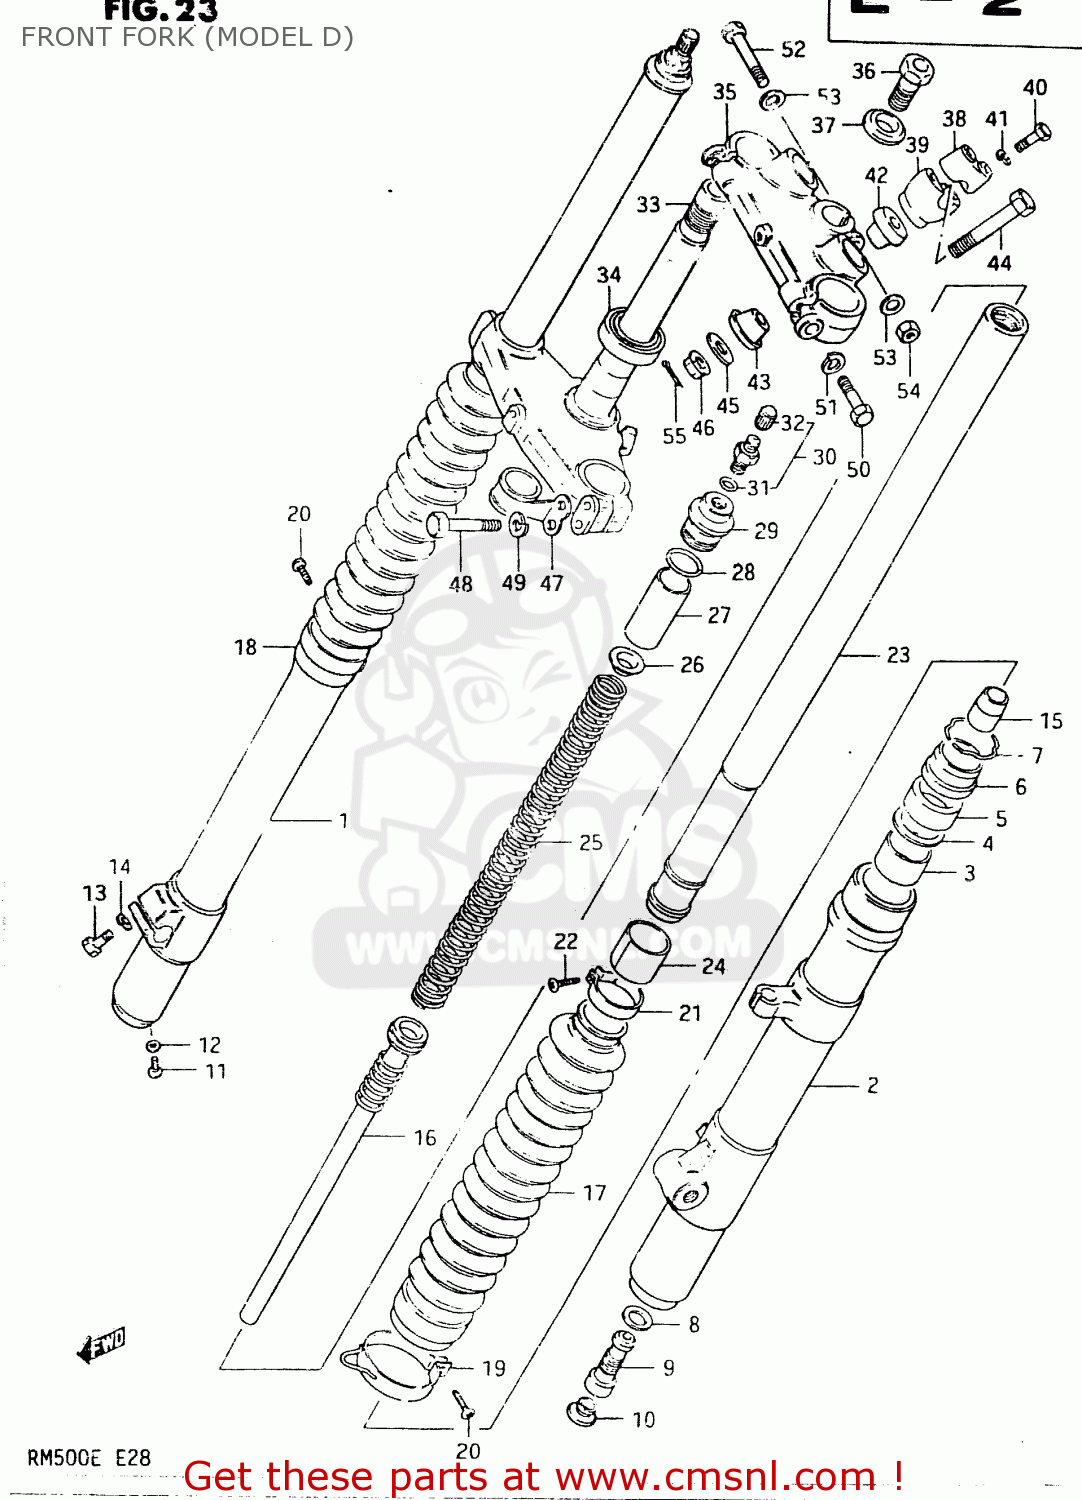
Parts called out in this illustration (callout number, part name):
1	TUBE,OUTER,RIGHT
2	TUBE,OUTER,LEFT
3	METAL,SLIDE
4	WASHER
5	SEAL,OIL
6	SEAL,DUST
7	RING,STOPPER
8	GASKET,FORK CYLINDER
9	VALVE,DF
10	CAP,FRONT FORK DF
11	SCREW 4X6
12	GASKET,DRAIN,PLUG (NAS)
13	BOLT (8X30)
14	WASHER,LOCK,8.
15	PIECE,FRONT FORK OIL LOCK
16	CYLINDER,FRONT FORK
17	BOOT,FRONT FORK COVER
18	BAND,BOOT,UPPER
19	BAND,FRONT FORK BOOT
20	SCREW
21	BAND,FRONT FORK BOOT
22	SCREW 4X10
23	TUBE,INNER
24	PISTON
25	SPRING,FRONT FORK
26	GUIDE,SPRING
27	SPACER,FRONT FORK SPRING
28	O RING
29	CAP,FORK INNER TUBE
30	VALVE,FRONT FORK AIR
31	O-RING
32	CAP,VALVE AIR
33	STEM,STEERING
34	BEARING
35	HEAD,STEERING STEM
36	BOLT
37	WASHER
38	HOLDER,HANDLE UPR
39	HOLDER,HANDLE LWR
40	BOLT
41	WASHER,LOCK,8.
42	DAMPER,UPR
43	DAMPER,LWR
44	BOLT,HANDLE HOLDER
45	WASHER,HANDLEBAR HOLDER
46	NUT
47	GUIDE,CABLE
48	BOLT 8X40
49	WASHER,LOCK,8.
50	BOLT
51	WASHER,LOCK,8.
52	BOLT 8X50
53	WASHER
54	NUT
55	PIN 20X20
